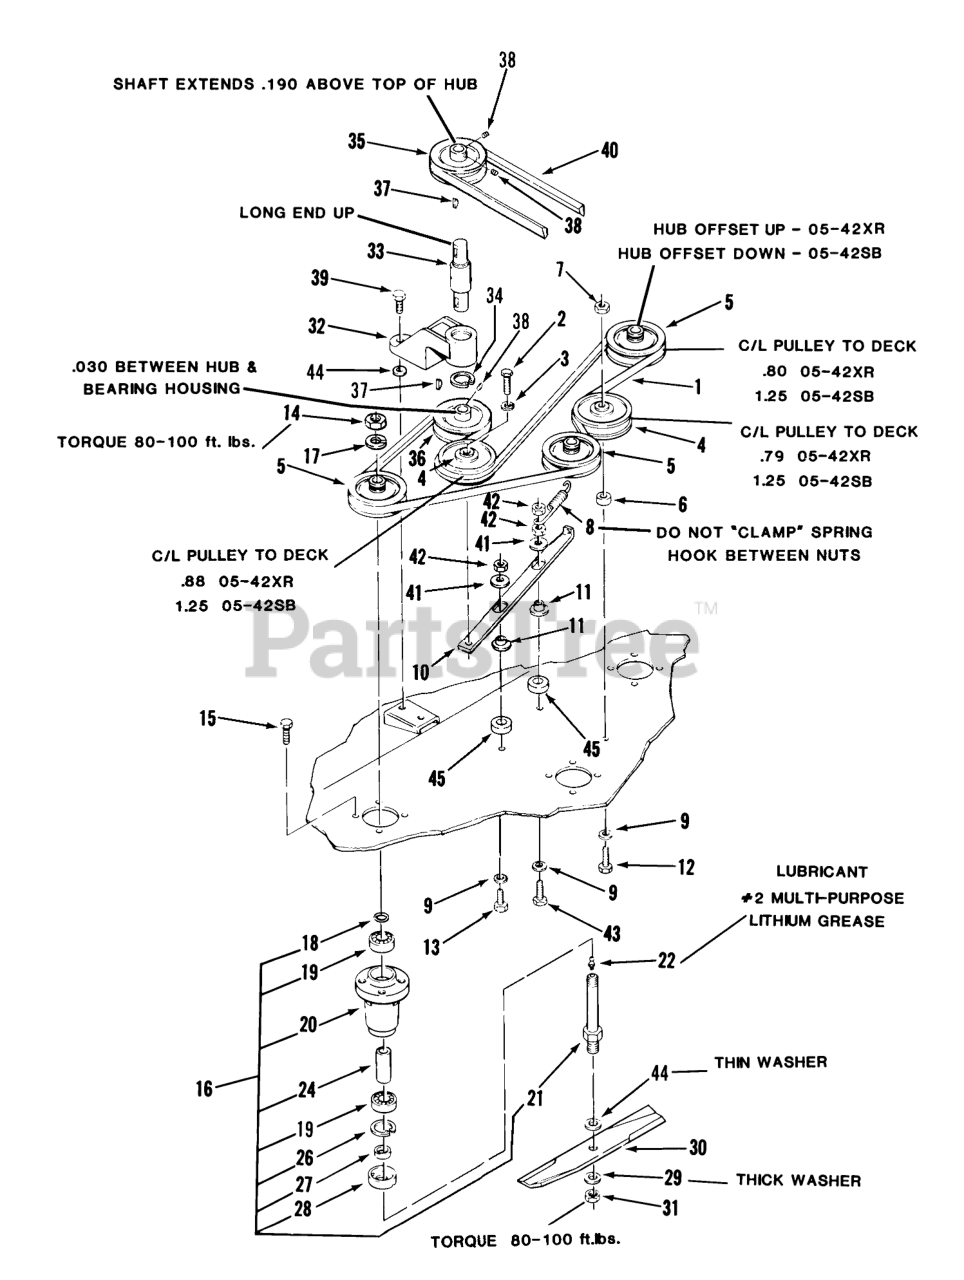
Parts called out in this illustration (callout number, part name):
1	V-BELT
2	BOLT HEX SPECIAL
3	LOCKWASHER
4	Idler Pulley
5	PULLEY
6	SPACER
7	Nut
8	SPRING-EXTENSION
9	WASHER
10	BAR-SLIDER
11	SPACER-BUSHING
12	Bolt
13	Bolt
14	Jam Nut
15	Bolt
16	Spindle Assembly
17	Lockwasher
18	O RING
19	BEARING-BALL
20	HOUSING-SPINDLE
21	Spindle Shaft
22	Zerk
26	Ring-Snap
27	SPACER-BLADE
28	CUP-SPINDLE
29	SpeciaI Washer
30	BLADE KIT
31	Nut-Jam
32	HOUSING DRIVE BRG R
33	BEARING-INT SHAFT
34	Snap Ring
35	PULLEY
36	PULLEY-SPLIT
37	KEY-WOODRUFF
38	Set Screw
39	Bolt
40	V-BELT
41	WASHER
42	NUT
43	Bolt
44	Washer
45	SPACER
